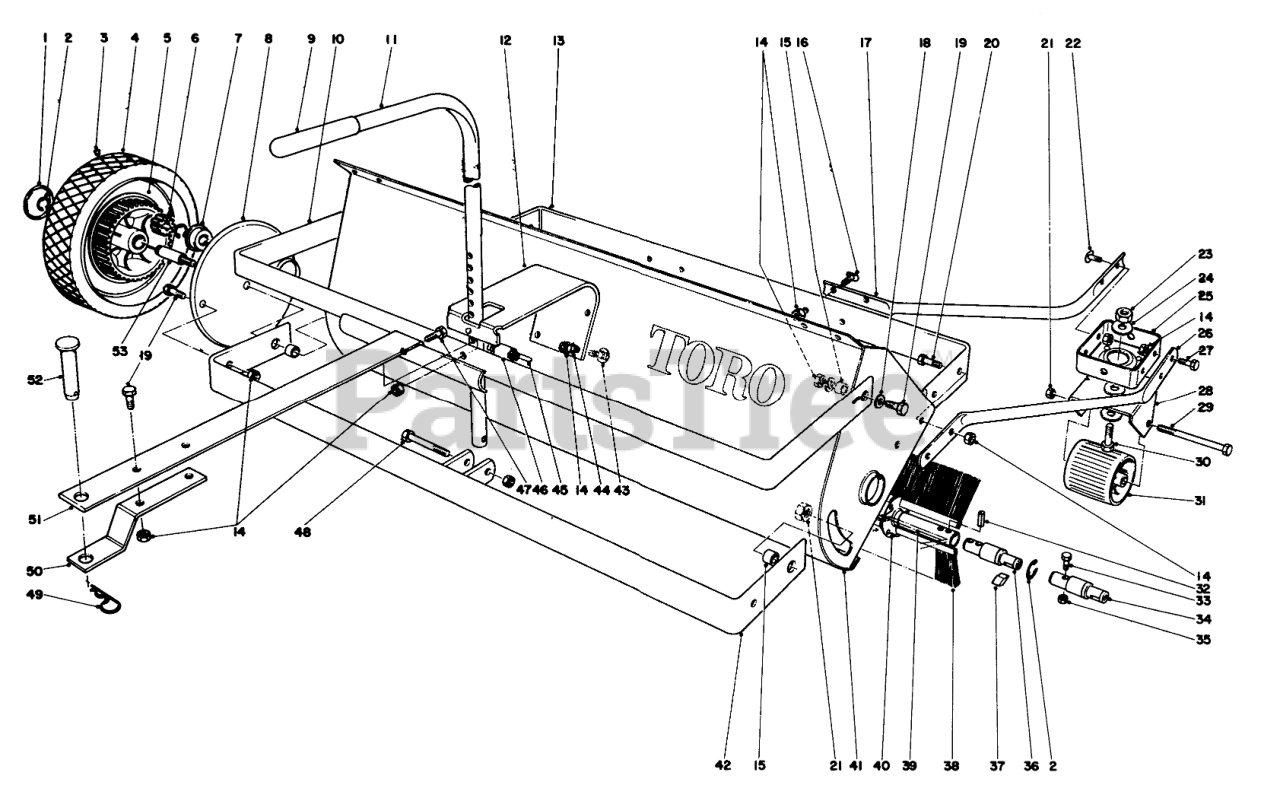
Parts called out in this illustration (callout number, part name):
1	Hub cap
2	Retaining ring
3	Oiler
5	Wheel
6	Pinion gear
7	Bearing
8	Shield
10	Hitch brace
11	Height adjustment hdl.
12	Bracket
13	Support bar
14	Nut
15	Spacer
16	Bolt, special
17	Inner support brace
18	WASHER-FLAT
19	SCREW-HH
20	SCREW-HH
21	Nut
22	Tube bolt
23	Locknut
24	Flatwasher, special
25	Caster wheel plate
26	Outer support brace
27	SCREW-HH
28	Caster wheel bracket
29	Special bolt
30	SCREW-HH
31	Caster wheel
32	PIN-ROLL, SLOTTED
33	SCREW-HH
34	Stud axle
35	Locknut
36	Stud Axle
37	Pinion pawl
38	Brush
39	Brush axle assembly
40	Brush retaining spring
42	Protector bar
43	SCREW-CARR
44	WASHER-LOCK
45	Spring
46	Spring tube
47	SCREW-HH
48	SCREW-HH
49	Klip Pin
50	Hitch bracket
51	Drawbar hitch
52	Hitch pin
53	Wheel axle
